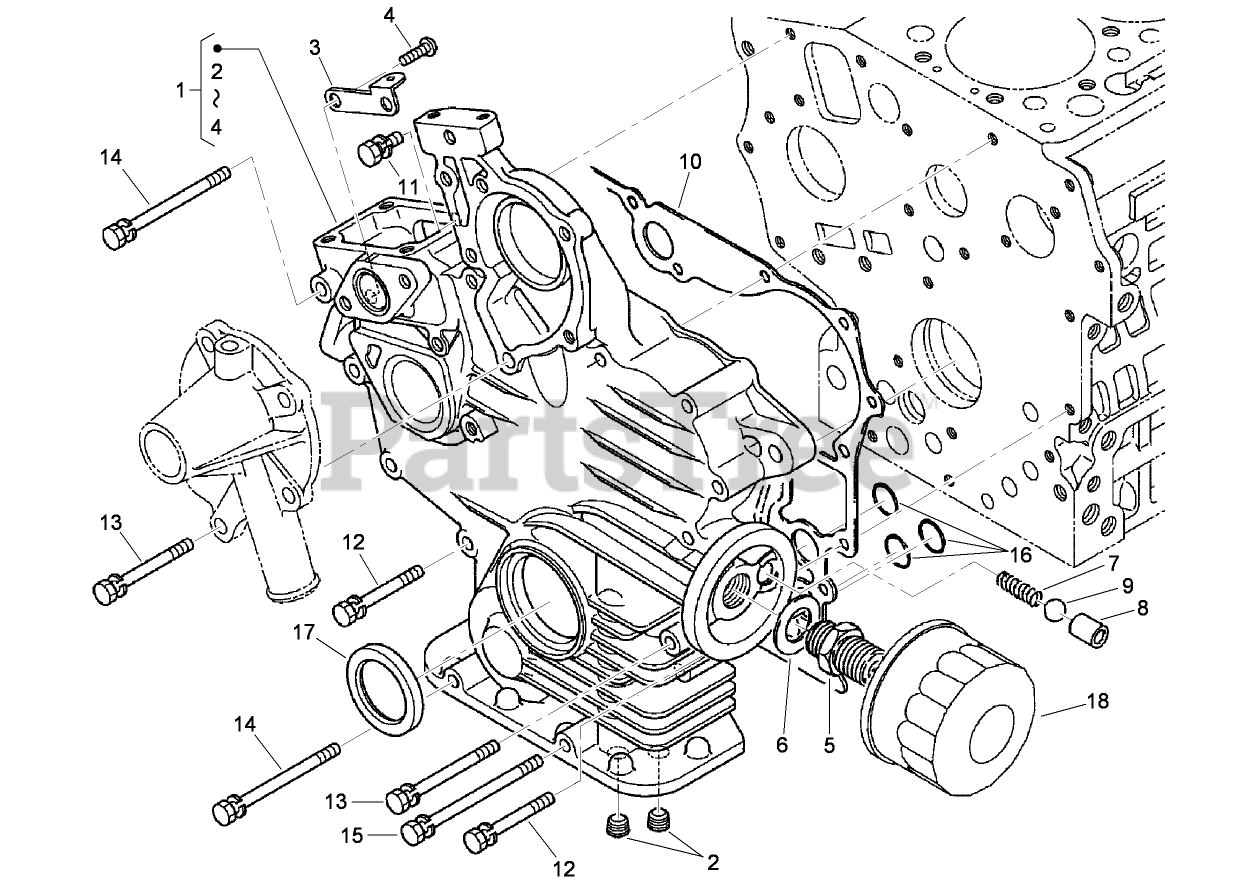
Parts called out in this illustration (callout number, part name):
1	CASE-GEAR
3	STAY-SPRING, START
5	JOINT-PIPE
6	WASHER-PLAIN
7	SPRING
8	SEAT-VALVE
10	GASKET-GEARCASE
16	O-RING
17	SEAL-OIL
18	CARTRIDGE-FILTER, OIL
